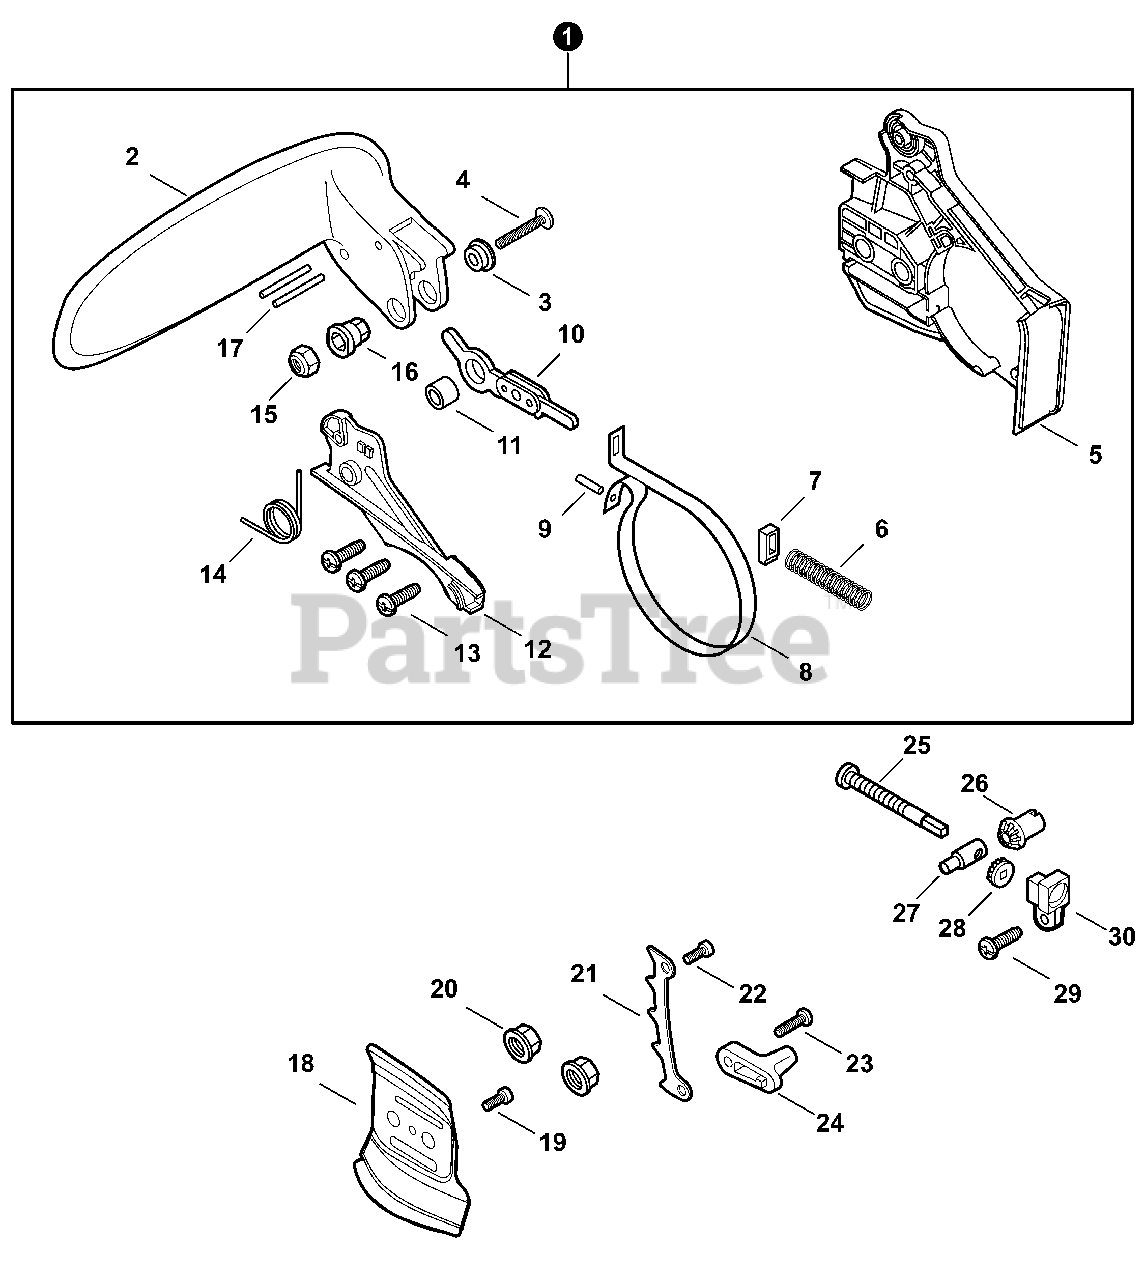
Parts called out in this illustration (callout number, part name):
1	BRAKE ASSY, CHAIN
2	LEVER, BRAKE - ORANGE
3	COLLAR 5.3×10×13×L5
4	SCREW 5×32
5	GUARD, SPROCKET
6	SPRING, COMPRESSION
8	BAND, BRAKE
9	PIN, SPRING 3x-9.8
10	CONNECTOR, BRAKE
11	SPACER 8×12×9
12	COVER, BRAKE
13	SCREW 4×12
14	SPRING, TORSION
15	NUT, LOCK M5
16	COLLAR 5
17	PIN 3×26
18	PLATE, GUIDE - INNER
19	SCREW 4×10
20	NUT, FLANGE M6
21	SPIKE, BUMPER
22	SCREW, TAPPING 5×20
23	SCREW, TAPPING 5×20
24	CHAIN CATCHER
26	GEAR, BEVEL
27	TENSIONER, CHAIN
28	GEAR, BEVEL
29	SCREW 4×12
30	COLLAR 8
